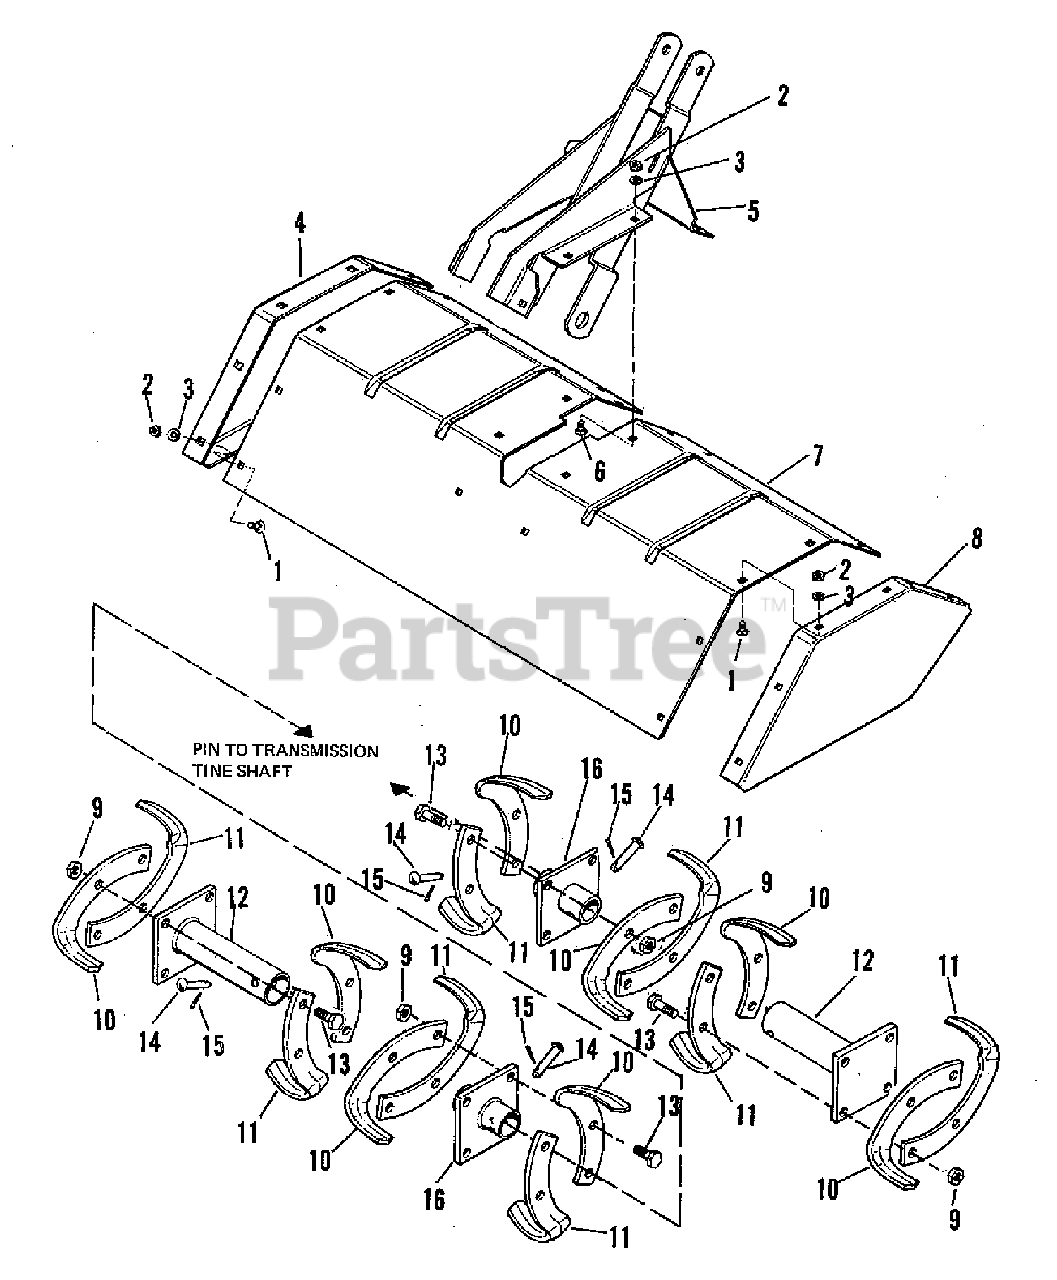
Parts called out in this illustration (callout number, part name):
1	BOLT, Carriage, 5/16-18 x 1/2
2	NUT, Full Hex, 5/16-18
3	WASHER, Lock
4	END PLATE DEFLECTOR, L.H.
5	SUPPORT ASSEMBLY
6	BOLT, Carriage, 5/16-18 x 3/4
8	END PLATE DEFLECTOR, R.H.
9	NUT, Lock, 7/16-20
10	TINE BLADE, R.H.
11	TINE BLADE, L.H.
12	TINE HUB ASSEMBLY
13	SCREW, Hex Cap, 7/16-20 x 1-1/4
14	TINE SHAFT PIN
15	PIN, Cotter, 1/8 x 3/4
16	INNER TINE PLATE ASSEMBLY
